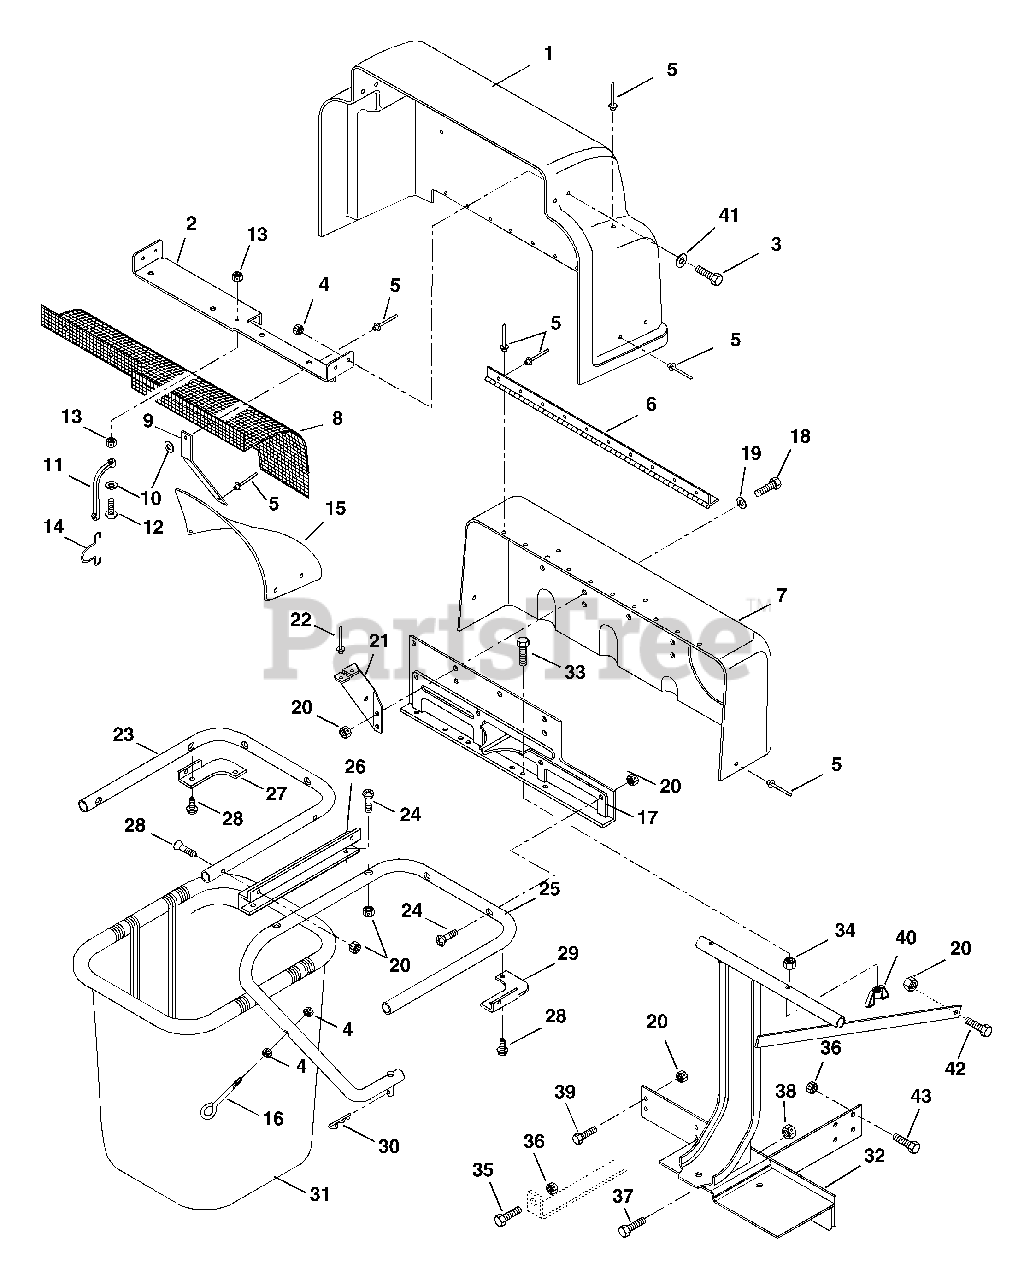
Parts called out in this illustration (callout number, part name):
1	Hinged Cover w/Decals
2	Cover Bracket
3	Bolt-Hex .25-20 x .50 Grade 2
4	Nut-Locking-Center .250-20
5	Rivet-Pop .187 x .402
7	Stationary Cover
10	Washer-Flat-Steel .219 x .50 x .049
11	Battery Strap
12	Screw-Machine 10-24 x .88
13	Nut-Locking Top 10-24
14	Hook
16	Eyebolt
17	Mounting Bracket
18	Bolt-Hex .31-18 x .88 Grade 2
19	Washer-Flat-Steel .328 x .875 x .062
20	Nut-Locking .312-18
21	Brace
22	Rivet-Pop .187 x .527
23	Center Tube
24	Screw-Machine .31-18 x 1.50
25	Right Tube
26	Tube Bracket
27	Left Hand Corner Bracket
28	Screw-Tapping .31-18 x .50
29	Right Hand Corner Bracket
30	Pin-Hair Internal .08 x .38 x 1.42
31	Grass Bagger Basket
32	Bagger Frame
33	Bolt-Hex .31-18 x 1.50 Grade 2
34	Nut-Hex .31-18 Grade 2
35	Bolt-Hex .38-16 x 1.25 Grade 5
36	Nut-Locking-Center .38-16 Grade 2
37	Bolt-Hex .50-13 x 1.00 Grade 5
38	Nut-Locking-Center .50-13
39	Bolt-Hex .31-18 x 1.00 Grade 5
40	Nut-Wing .312-18
41	Washer-flat-Steel .281 x .62 x .065
42	Bolt-Hex .31-18 x 1.25 Grade 5
43	Bolt-Hex .38-16 x 1.00 Grade 5
